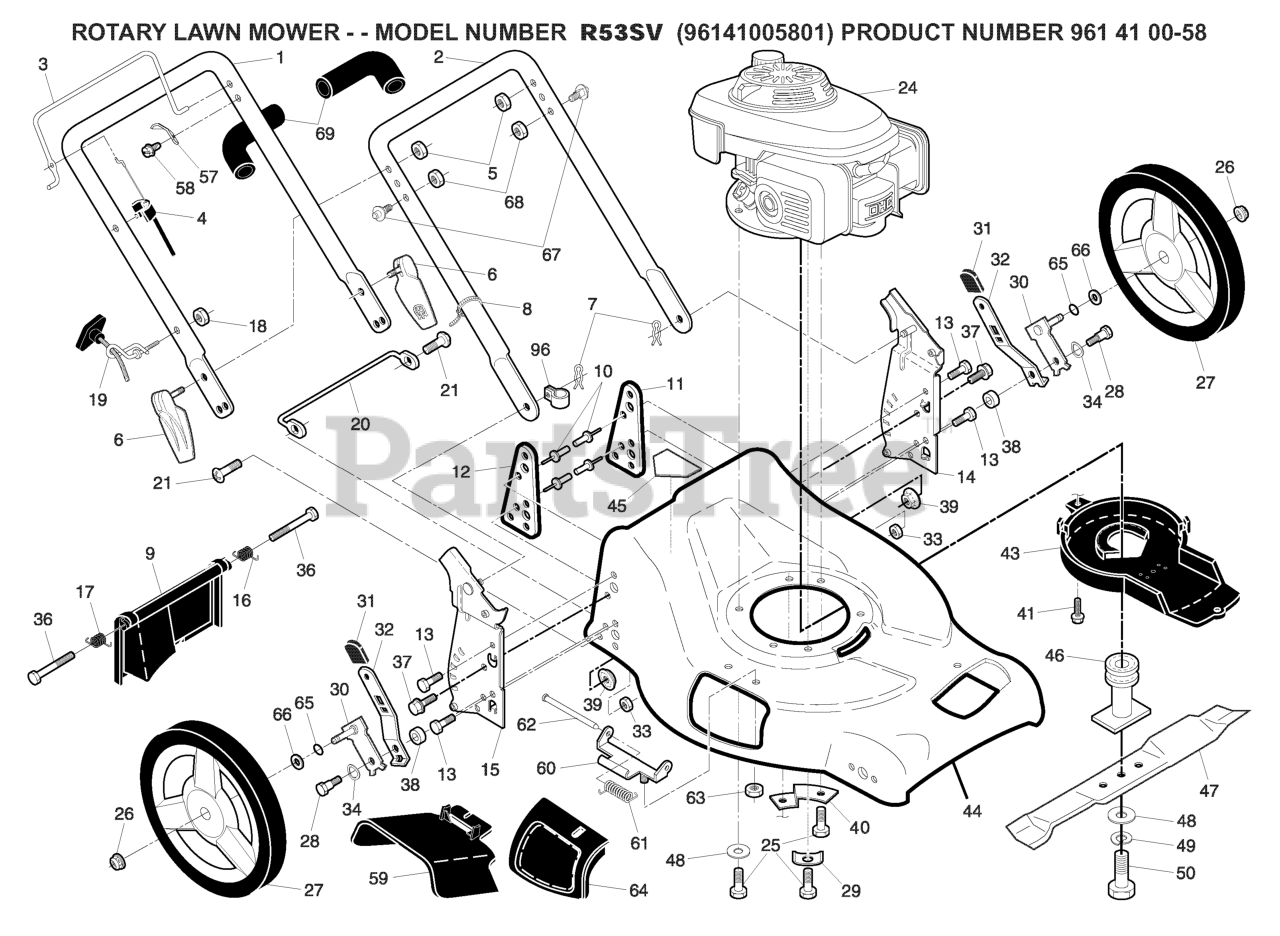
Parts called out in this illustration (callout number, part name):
2	HANDLE.LOWER.ECON.PNT
3	BAIL.DSTRT.FL.AW.CREAS.ORANGE
4	CABLE.ENGINE BRAKE.MZR
6	ASM.QUICK.RELEASE
7	HAIRPIN COTTER
8	TIE GUIDE
9	REAR DOOR ASSEMBLY
10	RIVET BLIND
11	SUPPORT BRACKET LH
12	BRACKET.SUPRT.RH.21.FWGD
13	SCREW 14-20 X 5/8
14	BRKT.ASM.HNDL.21FGD.EZ
15	BRKT.ASM.HNDL.21FGD
16	SPRING.REAR.DOOR.EZ.21.LT
17	SPRING.REAR.DOOR.EZ.21.RT
18	NUT
19	RB GUIDE.ROPE.STD.BLK.ZIN WSL
21	SCREW
25	BOLT 3/8-16X1-1/8
26	NUT.HEX.FLANGE.3/8-16.LOCKNUT
27	WHEEL ASSY
28	SHOULDER BOLT 5/16-18
29	WASHER.ENGINE.BZP
30	ARM.ASM.AXLE.REAR.5/9.POS.BZP
31	SELECTOR KNOB
32	SELECTOR SPRING
33	NUT.71038.31-18.HEX.NYLOCK
34	WASHER.CURVED.CYLINDRICAL
37	BOLT.FIN.HEX.5/16-18X3/4
38	SPACER.HEIGHT.ADJUSTER
39	NUT.FLANGE.5/16
40	BRACKET
41	SCREW.HEX.WSH
43	DEBRIS SHIELD
44	KIT.HSG.21.FGD.MC.ORG.CE SYM
45	DECAL.INTERNATIONL.CUTFINGER
46	Blade Adapter / Pulley
47	BLADE.21.PUSH
48	WASHER,HARDEN
49	LOCKWASHER
50	SCREW, HEX HD 3/8-24 X 1-3/8
57	BRACKET UPSTOP
59	DEFLECTOR.CLIPPIN.21.FGD
60	BRACKET.ASM.HINGE.21.FWGD.
61	SPRING.TORSION
62	ROD.HINGE.21
63	LOCKNUT.NYLOC.1/4-20
64	DOOR.MULCH.21.REAR.FWGD
65	O-RING..070X.487.NEOPRENE
66	WASHER.FLAT.1/2
67	STUD.QUICK.ADJUST
68	NUT.LOCK.5/16-18
69	GRIP.HANDLE.FOAM.WIDE.(1 SIDE)
96	CLIP.CABLE.BLK
